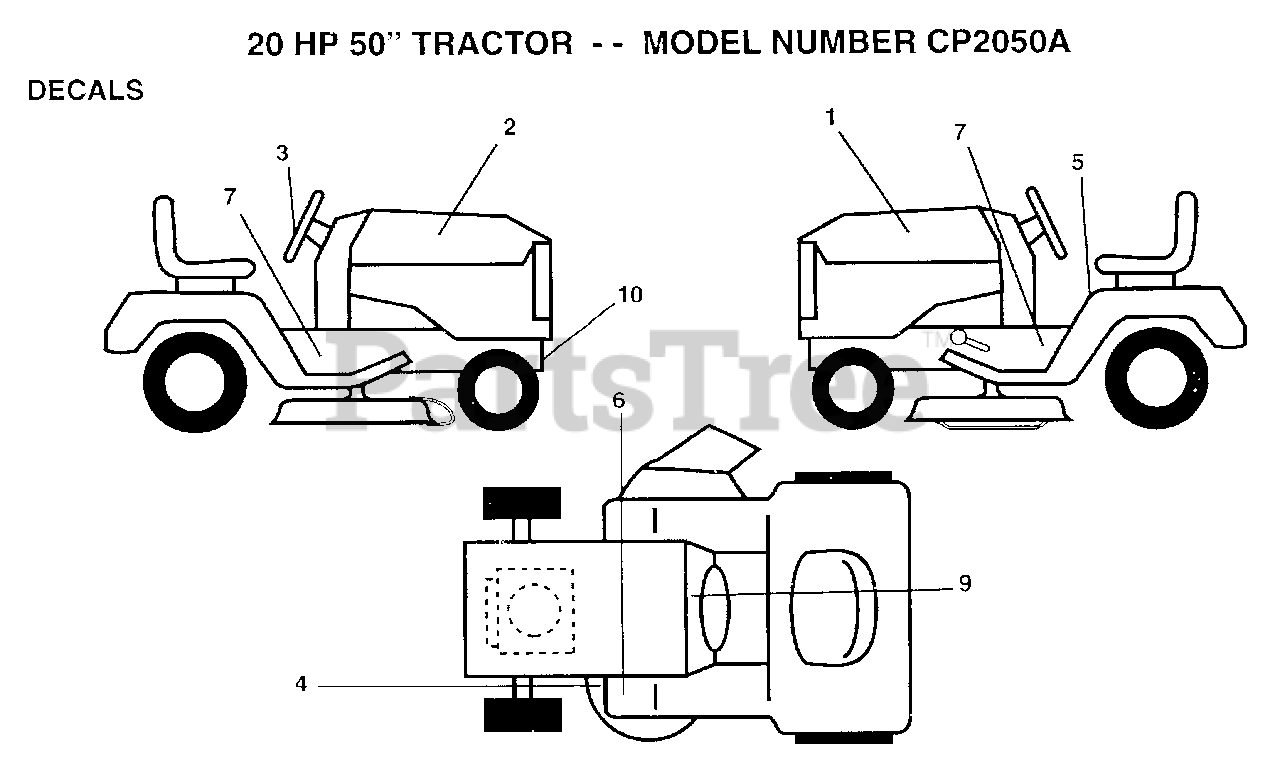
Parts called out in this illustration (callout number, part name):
1	DECAL.HOOD.LH
2	DECAL.HOOD.RH
3	DECAL.WHL.STRG.
5	DECAL
7	DECAL.CHASSIS 6SP
